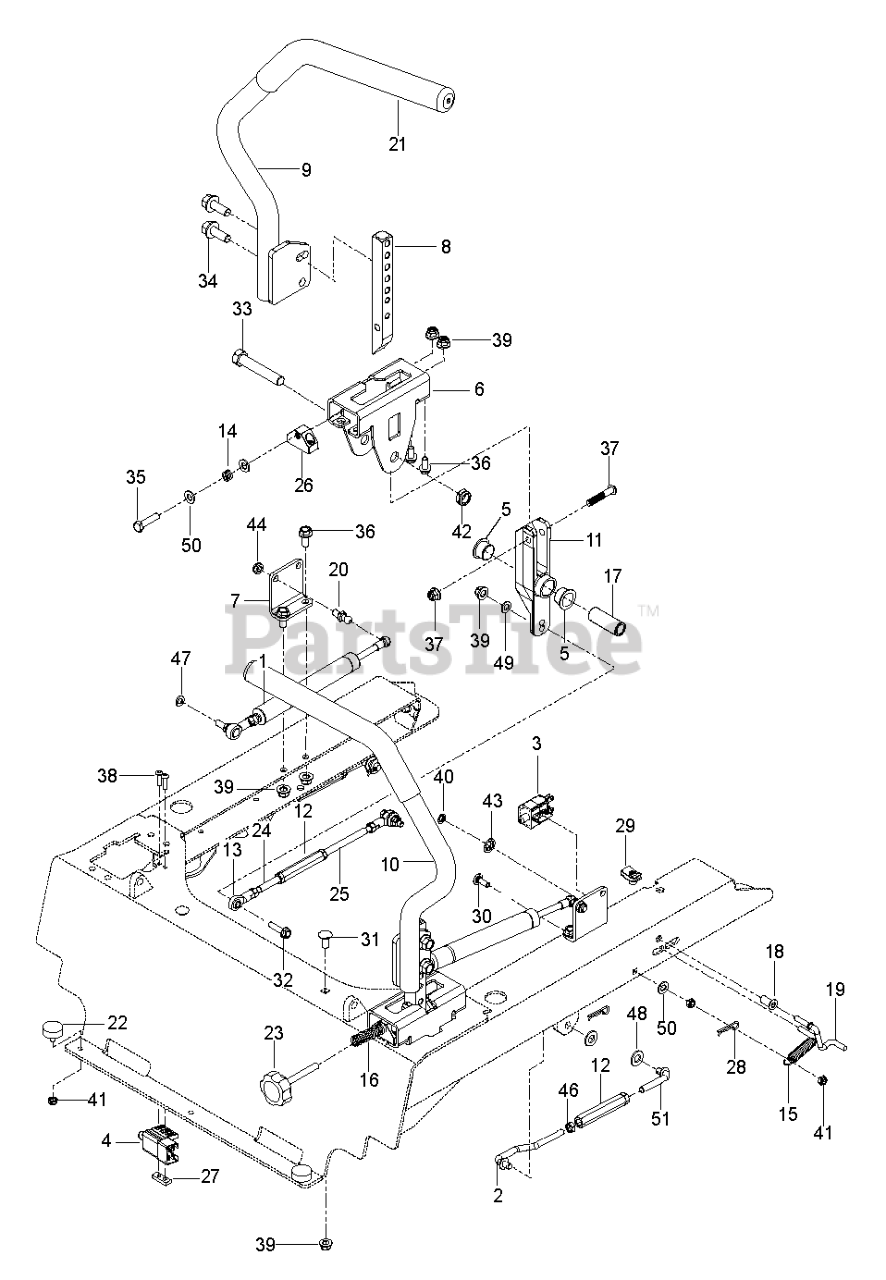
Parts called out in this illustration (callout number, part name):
1	ASSEMBLY, DAMPENER
2	LINKAGE SEAT STUT RH
3	SWITCH, BRAKE 3P
4	SWITCH INTERLOCKT
5	BEARING, FLANGE
6	BRACKET.CONTROL.NARROWSLOT.BLK
7	BRACKET.DAMPENER
8	LEVER, MOTION
9	LEVER.WITH GRIP.RT
10	LEVER.WITH GRIP.LT
11	LEVER.CONTROL.SHORT
12	TURNBUCKLE, 3/8
13	BALL JOINT, RIGHT HANDED
15	SPRING, EXTENSION
16	SPRING COMPRESSION 2.0
17	SPACER, PIVOT CONTROL
18	BUSHING, 1/4 FLANGE
19	LINK, SWITCH
20	STUD.BALL.10MM
21	RedMax TBD
22	BUMPER, 1/4-20 STUD, 1/4
23	KNOB
24	LINKAGE, CONTROL, FT
25	LINKAGE, CONTROL, RR
26	BLOCK TRACKING CONTROL ZTR
27	PLATE NUT ZTR
28	HAIRPIN #2
29	U-CLIP 5/16-18 NUT RETAINER
30	1/4-20X3/4 CARR BLT
31	BOLT 5/16C X 3/4" CARRIAGE
32	HHFS 5/16-18 X 1.25 TPBLT GD 5
33	HCS 1/2-13 X 2-3/4 GD 5 ZD
34	HHFS 3/8-16 X 1 GRD 5 ZD
35	BOLT.5/16-18X1-1/4 FULL.THREAD
36	HHFS 5/16-18 X 3/4
37	SCREW 5/16-18 X 1 3/4 BTN-HD
38	SCR #10-24 X .75 SKT HD BLK
39	5/16-18 NYLOC FLANGE NUT
40	NUT PUSH
41	JAM NUT 1/4C (2 2 PW01)
42	NUT 1/2-13 HEX JM NYL
43	NUT 3/8 PALNUT RTNG BLK PHOS
44	NUT.71038.31-18.HEX.NYLOCK
46	NUT 3/8-24 JAM
47	WASHER 5/16 LOCK
49	WASHER 5/16 FLAT
50	WASHER
51	LINKAGE SEAT LH
